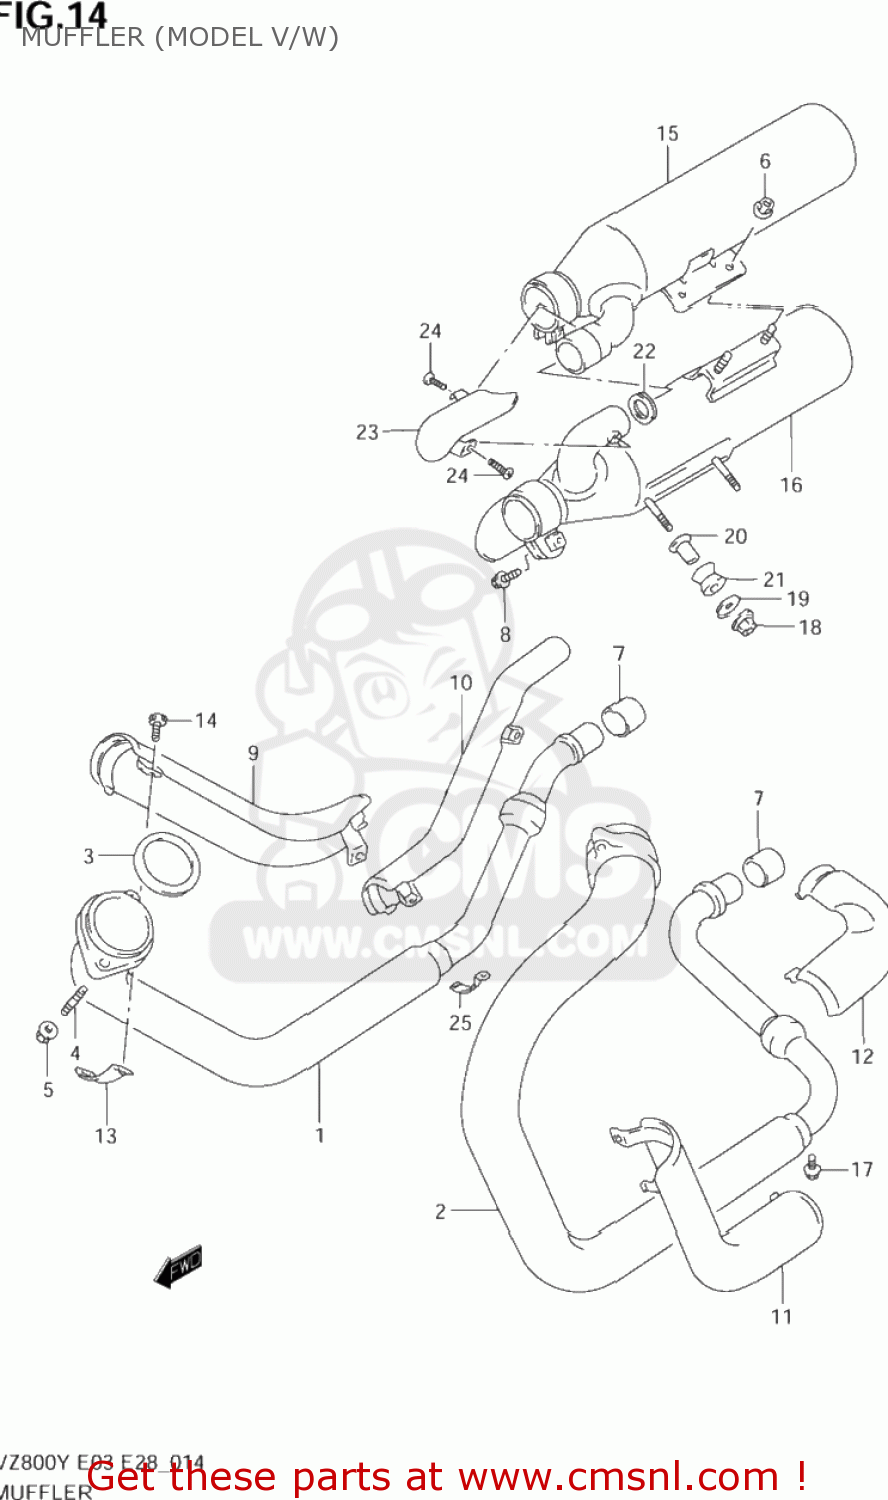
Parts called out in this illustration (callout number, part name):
1	PIPE,EXHAUST,R
2	PIPE,EXHAUST,L
3	GASKET,EXHAUST PIPE (NAS)
4	BOLT,STUD
5	NUT
6	NUT
7	CONNECTOR,MUFFLER JOINT
8	BOLT(8X33)
9	COVER,EXHAUST PIPE,R FR
10	COVER,EXHAUST PIPE,R RR
11	COVER,EXHAUST PIPE,L FR
12	COVER COMP,EXHAUST PIPE,LEFT
13	CLAMP,EXHAUST PIPE COVER
14	BOLT(6X20)
15	BODY,MUFFLER,R
16	BODY,MUFFLER,LEFT
17	BOLT
18	NUT
19	WASHER (8.2X26X1.6)
20	SPACER(8.6X12X17.5)
21	CUSHION
22	GASKET,MUFFLER JOINT
23	COVER,MUFFLER
24	SCREW(6X10)
25	CLAMP,EXHAUST PIPE COVER,R RR
